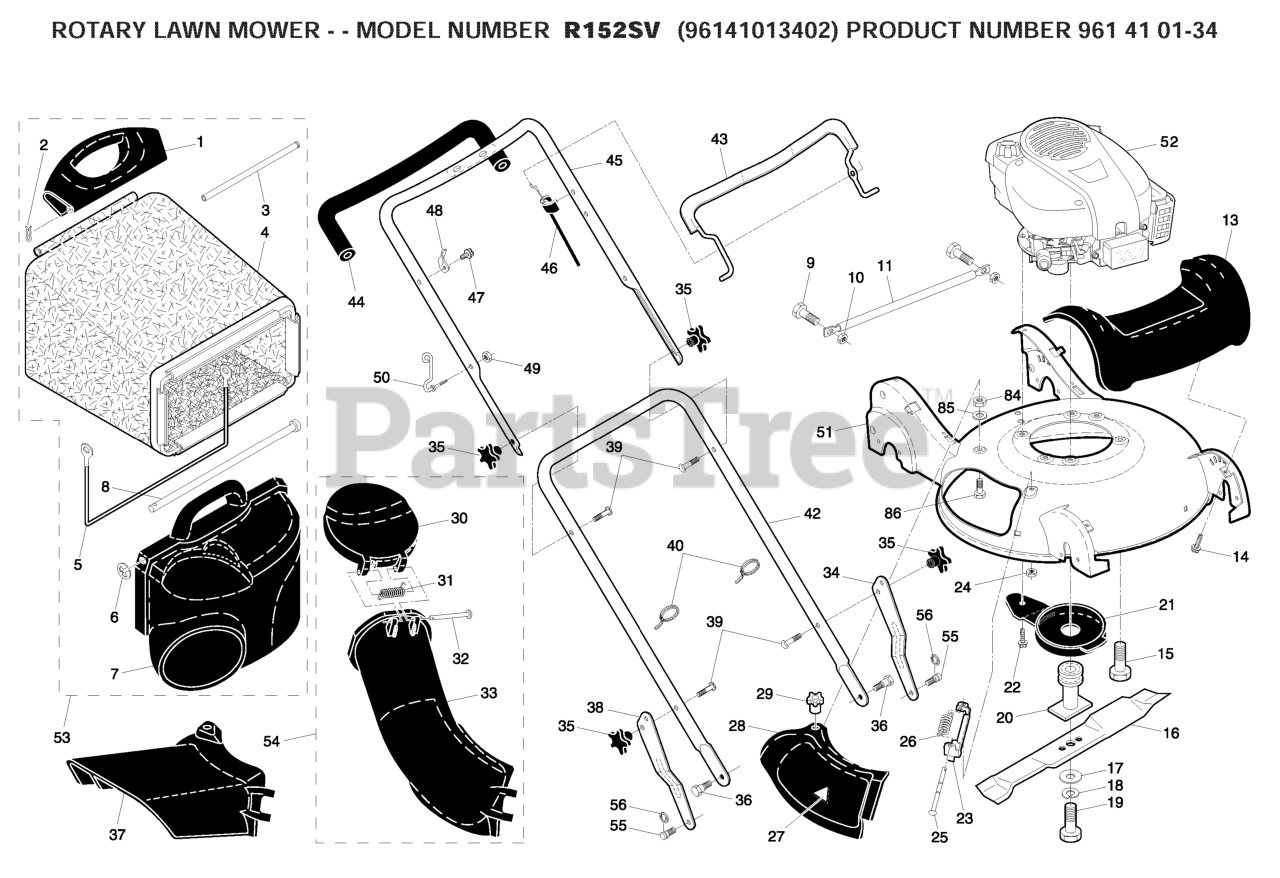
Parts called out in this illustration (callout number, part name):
1	HANDLE.GRASSBAG.REAR.H-GRAY
2	COTTER PIN (3 2)(2 2MC)
3	ROD.REAR.HANDLE.YELLOW
5	FRAME, GRASSBAG
7	DOOR, GRASSBAG
8	ROD, PIVOT
10	LOCKNUT.NYLOC.1/4-20
11	TUBE, REAR SKIRT
13	COVER.FRONT.21.HV.H-GRAY
14	SCREW, HEX WASHER HEAD
15	BOLT 3/8-16X1-1/8
16	Blade, 21"
17	WASHER,HARDEN
18	LOCKWASHER
19	BOLT.HD.HEAD.3/8-24X2.50 (2 2)
20	ADAPTER.BLADE
21	DEBRIS SHEILD
22	SCREW 1/4X20
23	BRACKET.ASM.HINGE
24	NUT.HEX.FLANGE.1/4
25	ROD.HINGE.1/4"3.82"
26	SPRING.MULCH.DOOR
27	DECAL.INTERNATIONL.CUTFINGER
28	MULCHER DOOR
29	KNOB.MULCH.DOOR
30	CHUTE.DOOR.21.HV.H-GRAY
32	ROD.HINGE.1/4"3.82"
33	DISCHARGE CHUTE PLASTIC
34	ADJUSTMENT BRACKET, LOWER LH
35	KNOB.HANDLE.STAR.HUSQ.GRAY
36	SCREW.5/16X.680.TRIM.H
37	GUARD.CLIP.ON.21.HV.GRAY
38	BRACKET.ADJ.LOWER.HDL.RT.GREY
39	BOLT, HANDLE 5/16-18X1.75
40	TIE GUIDE
42	HANDLE.LOWER.GREY
43	BAIL CONTROL
44	GRIP.HANDLE.FOAM.WIDE.(1 SIDE)
45	HANDLE.ASM.UPPER.W/GRIP
46	CABLE.MZR.SNAP-IN
48	BRACKET
49	NUT
50	GUIDE.ROPE.WALK.MOWER
53	Grassbag Assembly, Complete
54	CHUTE.LOWER.ASM.WALK.MOWER
55	STUD.SHOULDER.T45.BZP
56	E-RING 7/16 RE
84	NUT, HEX
85	LOCKWASHER
86	BOLT.CARRIAGE.1/4-20 X 7/8
